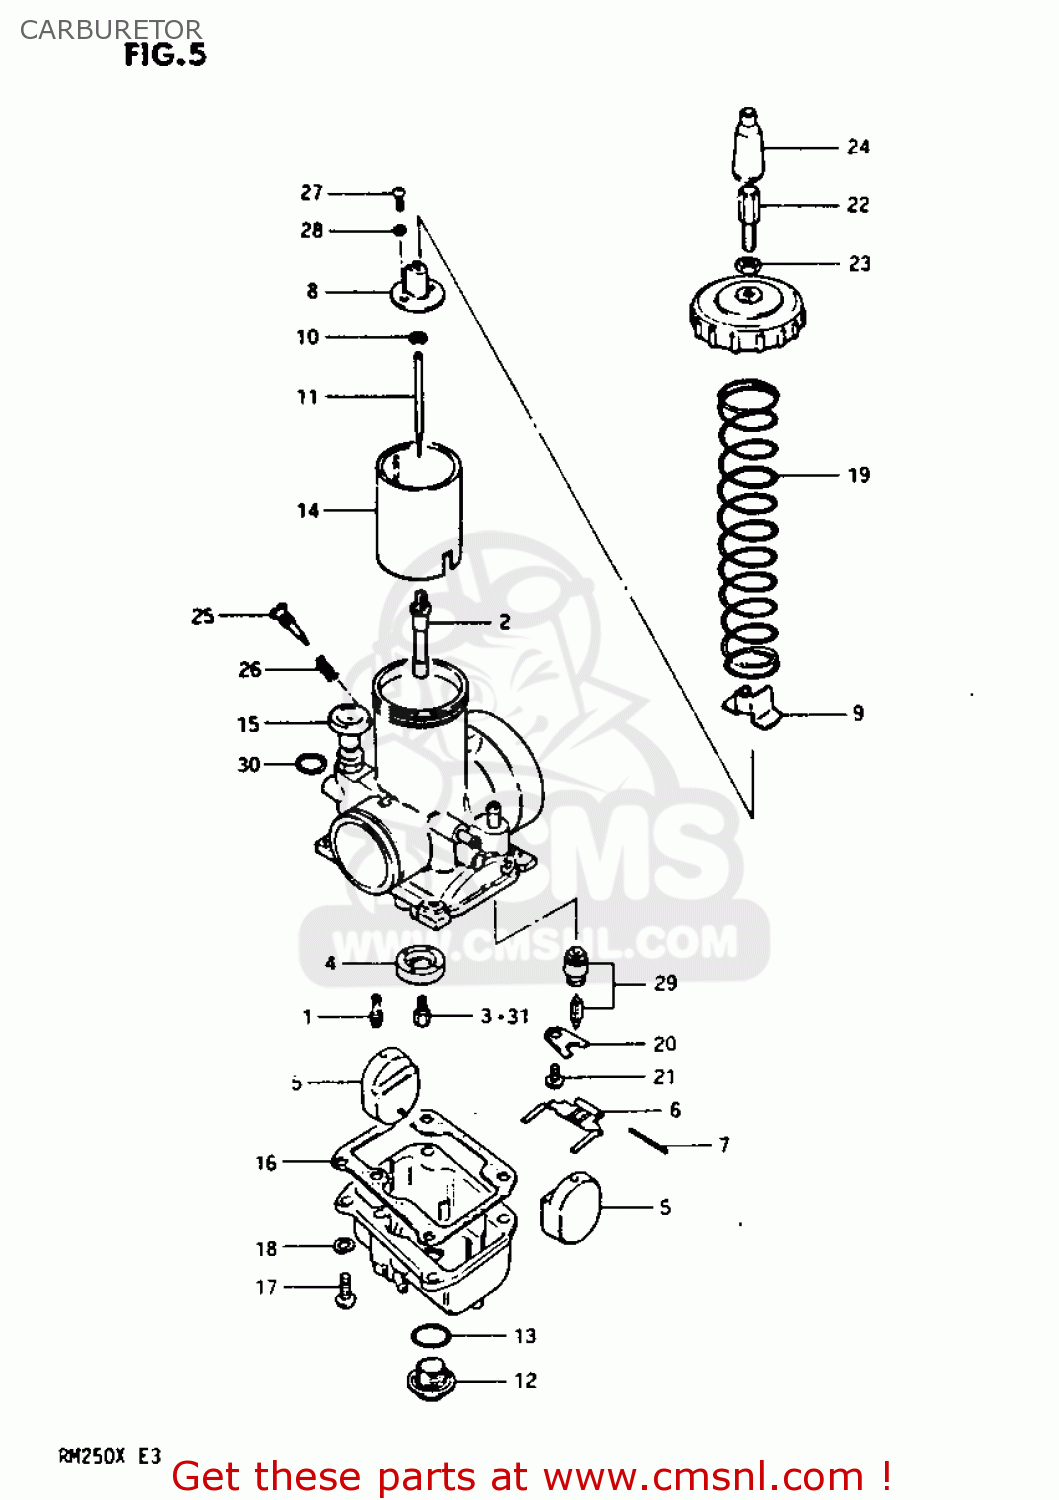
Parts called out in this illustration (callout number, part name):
1	JET,PILOT
2	JET,NEEDLE
3	JET,MAIN(320)
4	RING,MAIN JET FIXING
5	FLOAT
6	ARM,FLOAT
7	PIN,FLOAT
8	CONNECTOR
9	COVER,HOLDER
10	CLIP
11	NEEDLE JET
12	PLUG
13	O RING(D:1.5,ID:19.5)
14	VALVE,THROTTLE
15	VALVE ASSEMBLY,STARTER
16	GASKET,FLOAT CAHMBER (NAS)
17	SCREW
18	LOCK WASHER
19	SPRING
20	PLATE
21	SCREW 4X6
22	ADJUSTER,CABLE
23	NUT
24	CAP,CABLE ADJUSTER
25	SCREW,PILOT AIR
26	SPRING
27	SCREW
28	WASHER,LOCK
29	VALVE ASSEMBLY,NEEDLE
30	O-RING
31	JET
